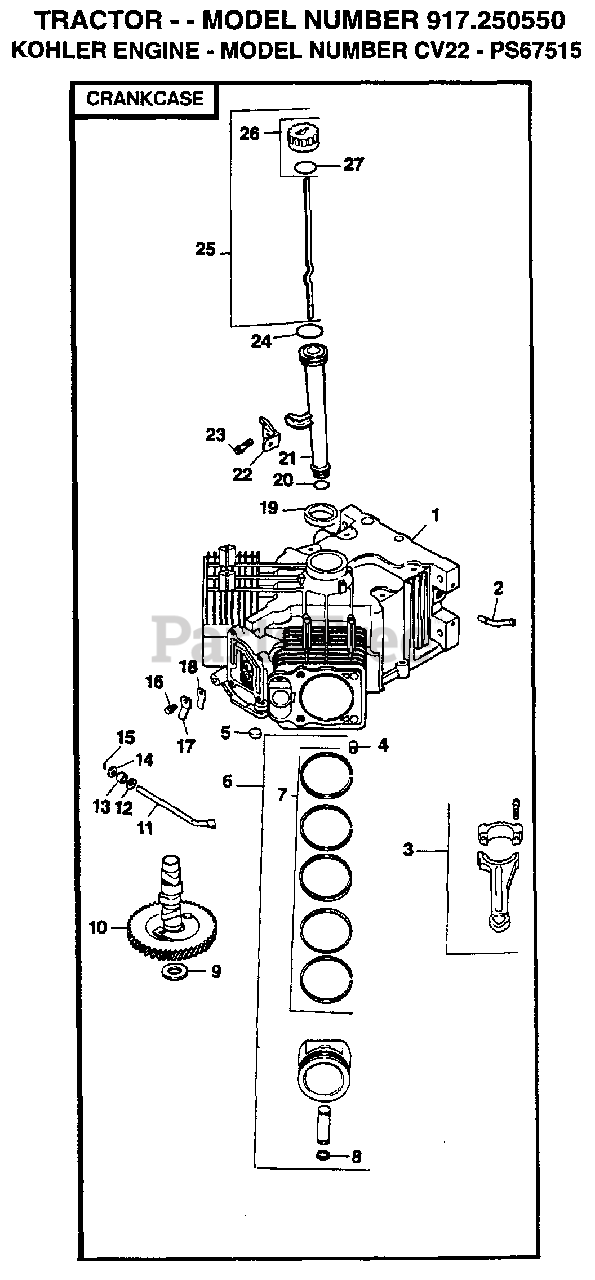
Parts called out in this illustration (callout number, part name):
3	CONNECTING ROD
4	PIN, DOWEL LOCATING
6	PISTON WITH RING SET
8	RETAINER, PISTON PIN
9	SHIM, CAMSHAFT,RED
9	SHIM, CAMSHAFT, BLACK
9	SHIM, CAMSHAFT, WHITE
9	SHIM, CAMSHAFT, BLUE
9	SHIM, CAMSHAFT, YELLOW
9	SHIM, CAMSHAFT, GREEN
9	SHIM, CAMSHAFT, GREY
11	SHAFT, GOVERNOR CROSS
12	WASHER, PLAIN 1/4
13	SEAL ,GOVERNOR CROSS SHAFT
16	SCREW, MOUNTING
17	RETAINER, REED
19	SEAL, OIL, FRONT
20	O-RING, LOWER OIL FILL TUBE
21	TUBE, OIL FILL
22	BRACKET, OIL FILL TUBE
24	O-RING, UPPER OIL FILL TUBE
25	DOPSTICK ASSEMBLY
26	KIT, OIL FILL CAP
27	O-RING, DIPSTICK
